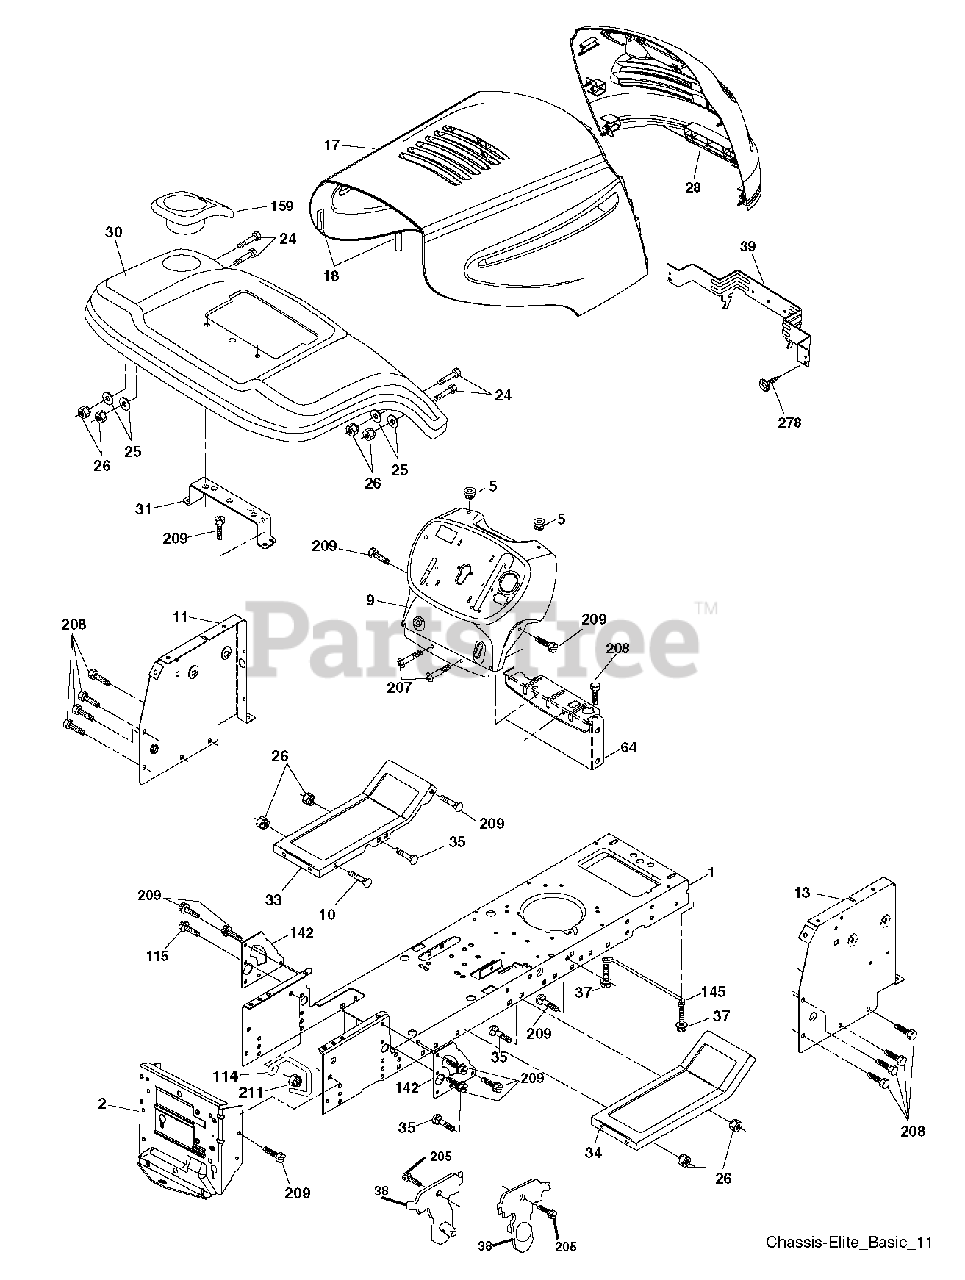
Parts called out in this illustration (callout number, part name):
1	CHASSIS STAMPING
2	DRAWBAR, 12GA
5	BUMPER.RUBBER.HOOD
11	PANEL.DASH.LH.LTX
17	HOOD.STEEL.ELITE.YELLOW
18	BUMPER.HOOD.LARGE.1.75"
25	WASHER
26	NUT
30	FENDER.LTST.W/SHFT.CUP.YELLOW
31	BRACKET FENDER
33	FOOTREST.LH.YELLOW
34	FOOTREST.RH.YELLOW
37	SCREW LT
38	BRACKET.ASM.PIVOT.MOWER.REAR
39	BRACKET PIVOT
64	DASH LOWER
115	SCREW.3/8-16
142	PLATE REINFORCEMENT
145	ROD.PIVOT.HOOD
159	CUPHOLDER.BLACK
205	SCREW LT
207	SCREW, 5/16-18 X 1/2
208	SCREW 3/8-16X1/2
209	SCREW, 3/8-16X3/4
211	NUT LOCK FLG 3/8-16 UNC
278	SCREW.#10 X 0.750.BOS (2 2)
